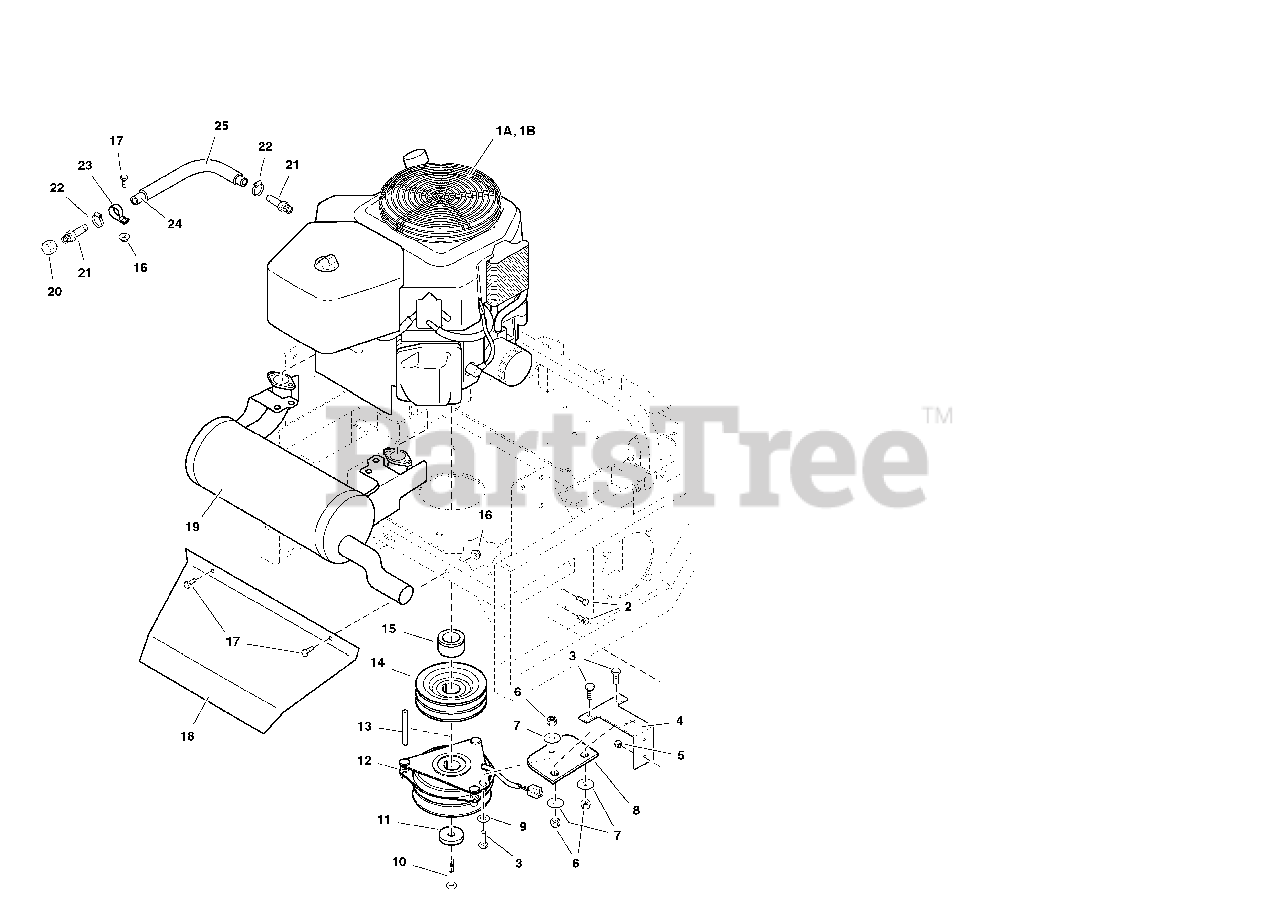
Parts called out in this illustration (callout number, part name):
1A	ENGINE, 21HP Kohler
1B	ENGINE, 23HP Kohler
2	CAPSCREW, Hex Hd, 5/16-18 x 3/4
3	CAPSCREW, Hex Hd, 3/8-16 x 1
4	CLUTCH ANCHOR
5	NUT, Hex, Nylon Lock, 5/16-18
6	NUT, Hex, Nylon Lock, 3/8-16
7	WASHER, Fender, 3/8
8	CLUTCH ANCHOR PAD
9	WASHER, 3/8
10	CRANKSHAFT BOLT, 7/16 x 2
11	RETAINER, Clutch
12	ELECTRIC CLUTCH
13	KEY, 1/4 Sq. x 3-1/2
14	CRANKSHAFT PULLEY
15	CRANKSHAFT SPACER
16	NUT, Hex, Serrated Flange, 1/4-20
17	CAPSCREW, Hex Hd, 1/4-20 x 3/4
18	MUFFLER HEAT SHIELD (for use with silver version muffler only)
19	MUFFLER
20	CAP, 3/8NPT
21	FITTING, 3/8NPT - 1/2 Str.
23	CLAMP, Vinyl
25	WIRE LOOM, 12"
